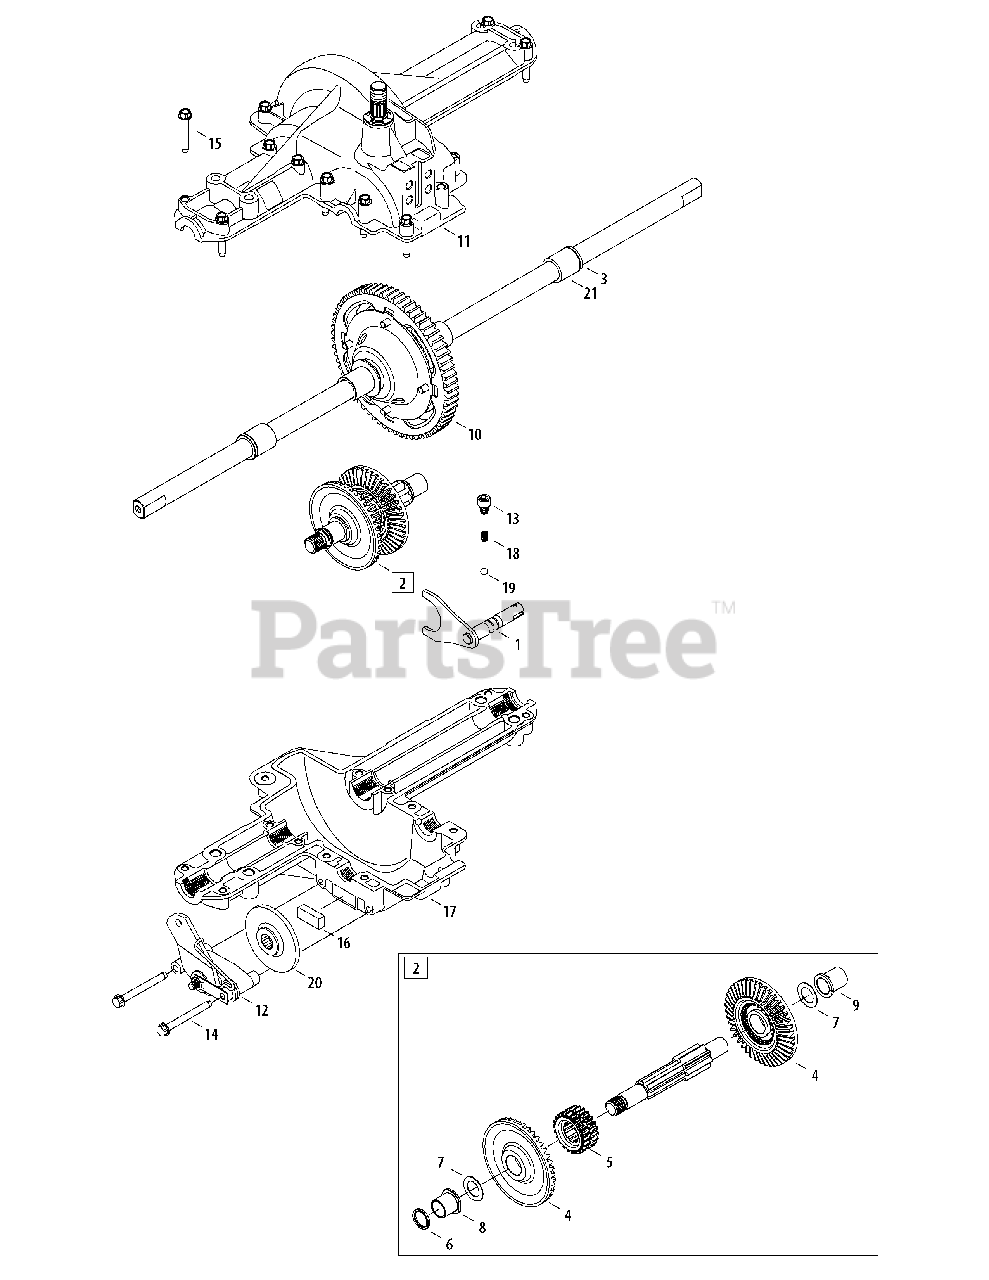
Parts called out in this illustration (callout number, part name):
1	Detent Shaft Assembly
2	Drive Shaft Ass'y (Incl. Ref. 3-9)
4	Bevel Gear 42T
5	Single Speed Clutch Collar
6	Seal .625 x .812 x .94
7	Shim Washer .625 ID x 1.0 OD x .030
7	Shim Washer .634 ID x 1.0 OD x 0.04
7	Shim Washer .630 ID x 1.0 x .020
7	Shim Washer .632" ID x 1.0 OD x .035
7	Shim Washer .632" ID x 1.0" OD x .025
8	Flange Bearing 5/8 x 3/4 x 3/4
9	Flange Bearing 5/8 x 3/4 x 15/16
10	Differential Assembly
11	Upper Housing
12	Brake Ass'y
13	S-Tap ping Screw 5/16-18 x .375
14	Hex Wash. Hd. Self-Tap Screw. 1/4-20
15	S-Tap ping Screw 1/4-10 x 1.625
16	Brake Puck
17	Lower Housing
18	Compression Spring
19	Ball Detent .250 Dia.
20	Brake Disc
21	Sleeve Bearing 3/4 ID x 1.0
